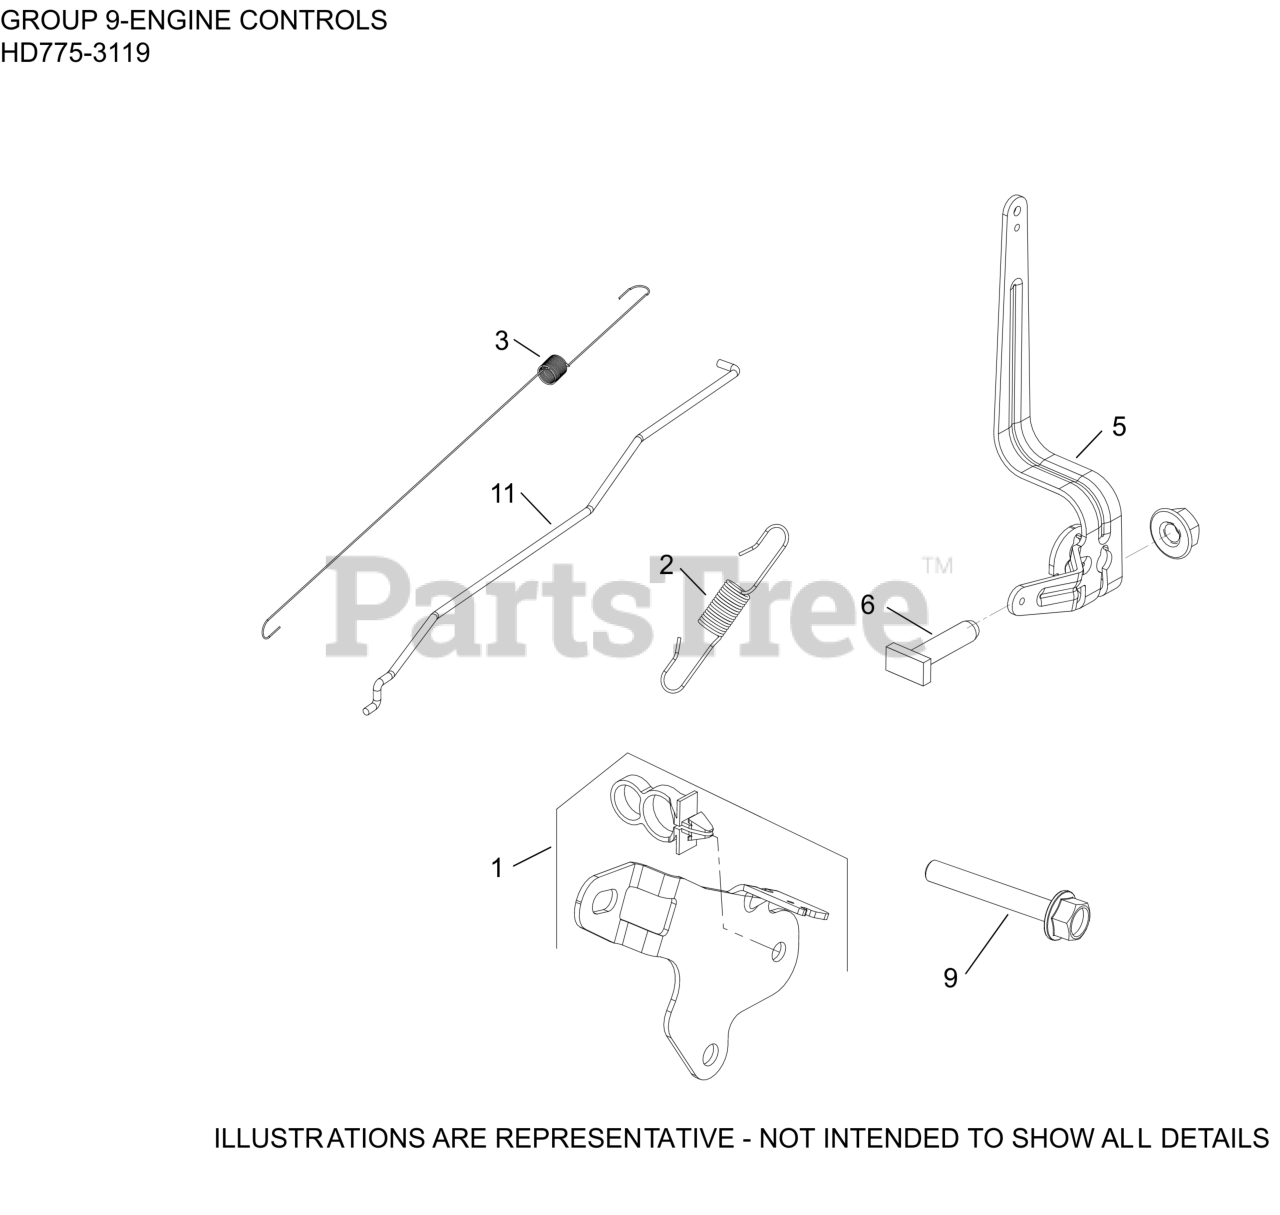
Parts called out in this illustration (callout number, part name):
1	BRACKET ASSEMBLY, FIX SPEED CONTROL
2	SPRING, EXTENSION (GOVERNOR)
3	SPRING, LINKAGE
5	LEVER, GOVERNOR
6	SCREW, RECTANGLE HEAD (M6)
9	SCREW, HEX FLANGE (M6)
11	LINKAGE, GOVERNOR
